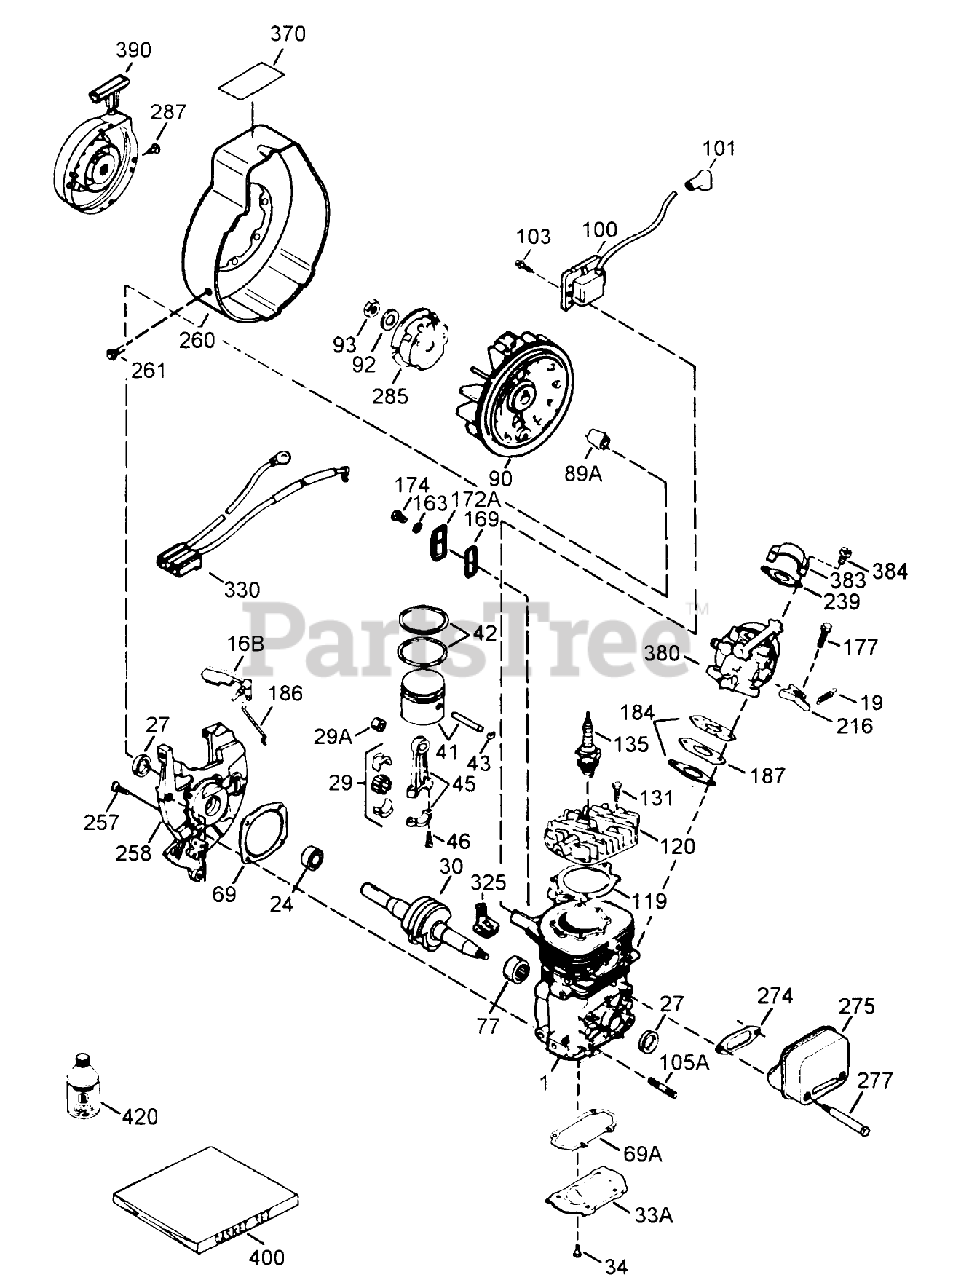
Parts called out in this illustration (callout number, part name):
1	Block Ass-y-Cylinder (Order short block if replacement is required)
16B	Vane-Air
19	Spring-Extention
24	Bearing-Ball
27	Seal-Oil
29	Needle Bearing and Liner Set (37 Needles)
29A	Bearing-Cartridge
30	Crankshaft
33A	Plate-Cover
34	Screw (T-25, 10-24 x 1/2)
41	Piston (Incl. Ref. #43)
42	Ring Set
43	Ring-Retaning
45	Rod Assy.-Connecting (Incl. Ref. #3, 3A 3B)
46	Bolt-Rod, Connecting
69	Gasket-Cover, Cylinder
69A	Gasket-Plate, Cover
77	Bearing-Cartridge
89A	Blade (20 inch)
90	Flywheel
92	Washer-Belleville
93	Nut-Flywheel
100	Solid State
101	Cover-Spark Plug
103	Screw
119	Gasket-Head, Cylinder
120	Head-Cylinder
131	Screw (T-30, 1/4-20 x 3/4)
135	Spark Plug-Resistor (R C J 8Y)
163	Washer
169	Cover-Compression, Release
172A	Cover-Release, Compression
174	Screw (T-25, 10-24 x 1/2)
177	Screw (5/32 Allen, 1/4-20 x 1)
184	Gasket-Carburetor
186	Governor-Link
187	Spacer
216	Lever-Adjusting, Rpm
239	2060A77 WIZARD ROTA
257	Screw (T-30, 1/4-20 x 5/8)
258	Base Assy.-Blower Housing (Incl. Ref. #10)
260	Blower Housing
261	Screw (1/4-20 x 1/2)
274	Gasket-Exhaust
275	Muffler (Incl. Ref. #274 277)
277	Screw (1/4-20 x 2-3/4)
285	Cup-Starter
287	Screw (8-32 x 21/64)
325A	Clip-Wire
330	Harness-Wire
370	Decal-Warning
380	Carburetor (Incl. Ref. #184A)
383	Baffle-Carburetor
384	Screw
390	Rewind Starter
400	Gasket Set
422	2-Cycle Oil (8oz)
